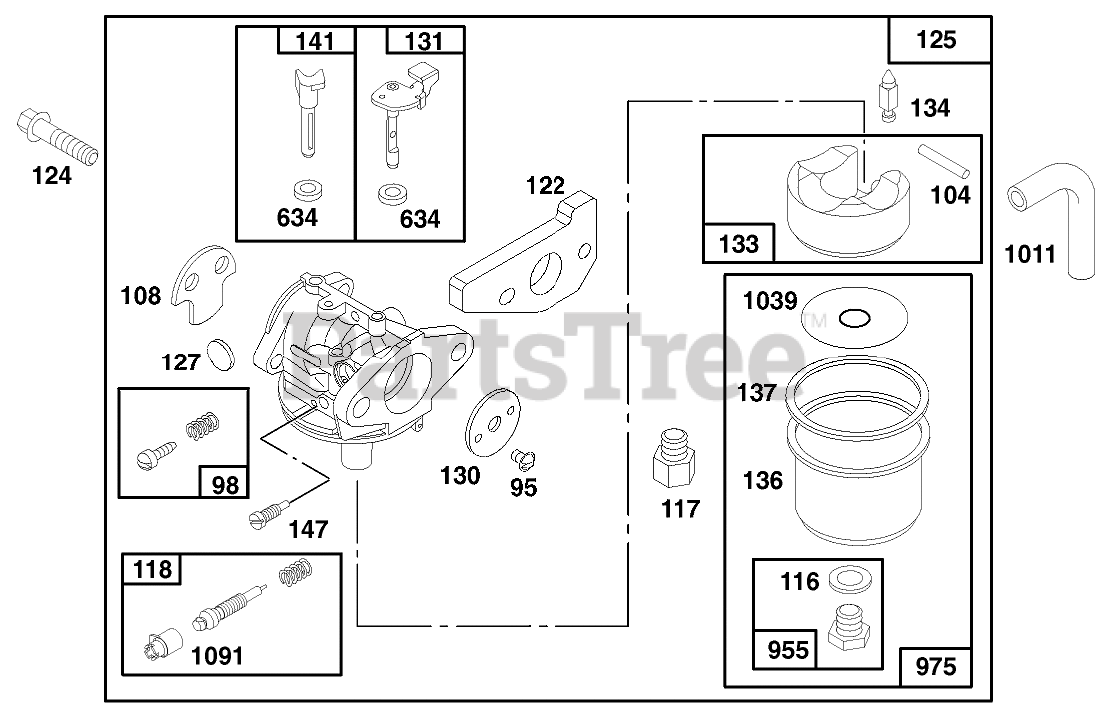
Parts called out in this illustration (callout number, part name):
37	GUARD - FLYWHEEL
95	SCREW - ROUND HEAD
98	IDLE ADJUSTING SCREW
104	FLOAT HINGE PIN
108	VALVE - CHOKE
116	SEALING GASKET
117	Jet-Main
118	VALVE/SPRING - NEEDLE
122	ADAPTER ASSEMBLY
124	HEX HEAD SCREW
125	ASSEMBLY - CARBURETOR
127	PLUG - WELCH
130	THROTTLE VALVE
131	THROTTLE SHAFT
133	FLOAT-CARBURETOR
134	Valve-Inlet(Includes Seat)
136	FLOAT BOWL
137	FLOAT BOWL GASKET
141	CHOKE SHAFT
147	JET - PILOT
634	SEAL WASHER
955	HEX HEAD SCREW
975	CARBURETOR BOWL ASM
1011	VENT TUBE
1039	FLOAT LIMITER
1091	CAP - LIMITER
